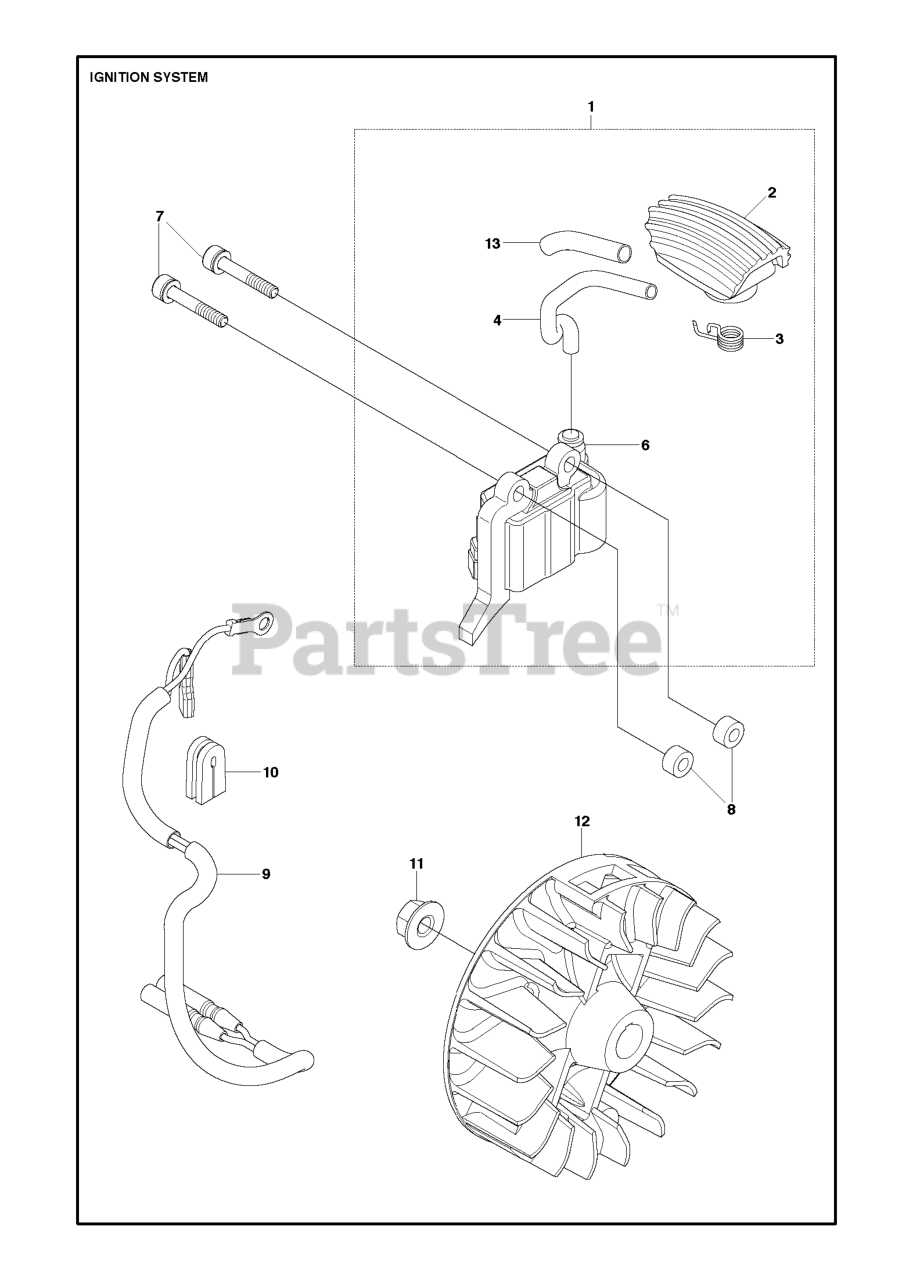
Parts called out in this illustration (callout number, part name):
1	LOCKNUT M8
2	WASHER BRB 8.4X17
6	BELT
8	PULLEY M53S / M48S
9	BLADE SUPPORT
11	SPRING M53 / M48
13	BOLT M53 / M48
